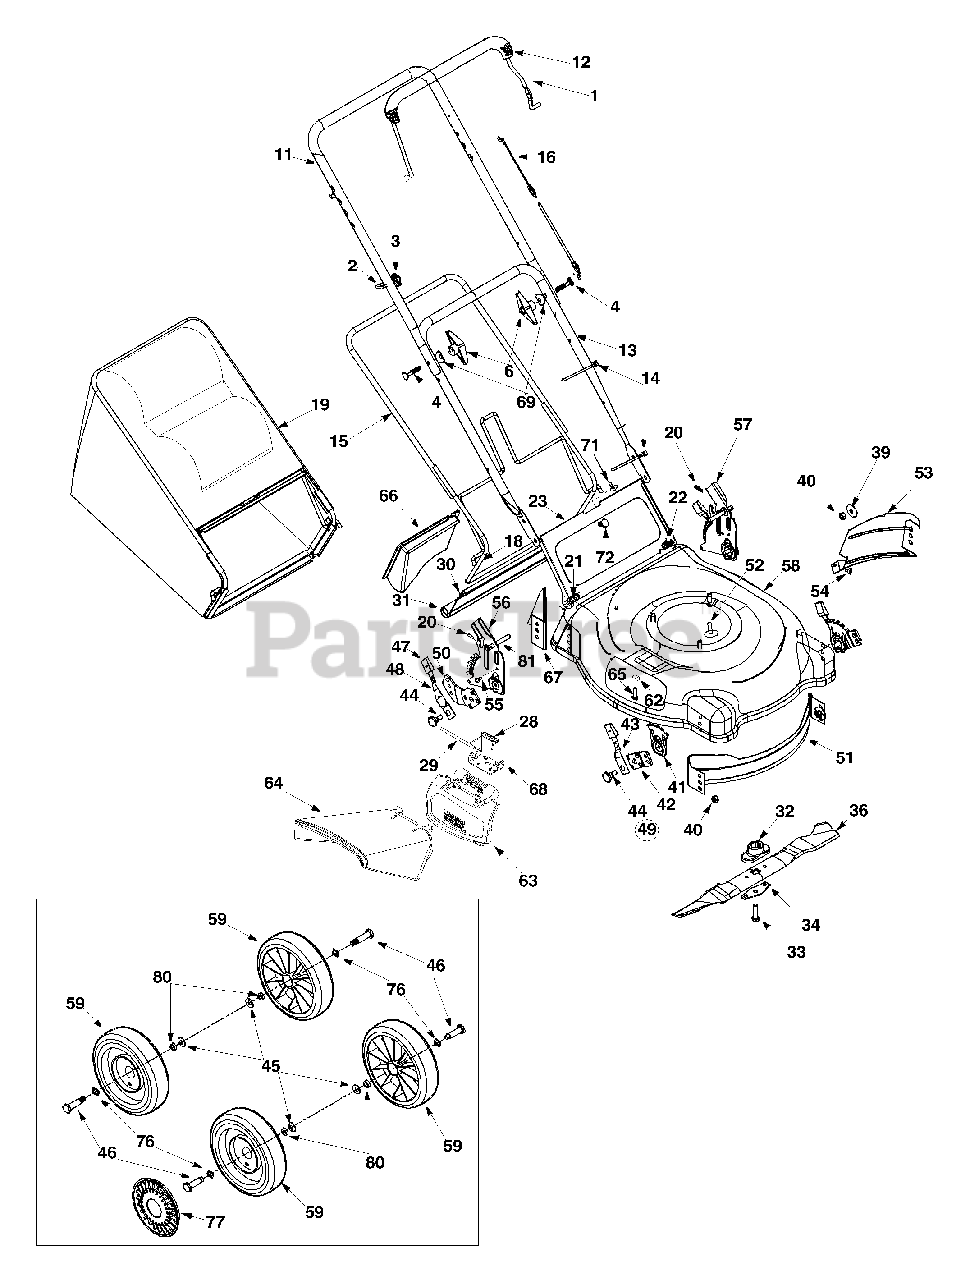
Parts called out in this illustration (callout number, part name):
2	Rope Guide
3	Handle Knob 1/4-20 Thd.
4	Curved Hd. Bolt 5/16-18 x 2"
6	Hand Knob
12	Bail Cover
14	Cable Tie
16	Control Cable - 40"
20	Int. Cotter Pin 5/16" Dia.
21	Door Spring - R.H.
22	Door Spring - L.H.
29	Hinge Pin
30	Wire Rod
31	Rear Flap
32	Blade Adapter
33	Hex Bolt 3/8-24 x 1.5" Lg.
34	Blade Bell Support
36	21" Mulching Blade
40	Flange Nut 3/8-16 Thd.
41	Height Adj. Plate
43	Front Spring Lever Ass'y. w/Knob
44	Shld. Bolt .5" Dia. x .357"
45	Bell Washer .38" I.D. x .88" O.D.
46	Axle Bolt
47	Spring Lever Knob
48	Rear Spring Lever
49	Height Adj. Assy. Comp. - RH
50	Pivot Bar R.H.
54	Torx Mach AB-Tap Scr. 1/4 x.62"
55	Hex Ind Wash. Scr. 1/4-14:.625
56	Handle Brkt. Ass'y.-RH
57	Handle Brkt. Ass'y.-LH
62	Bell Washer 1/4" I.D.
63	Hinged Mulching Plug
64	Chute Deflector: Side Discharge
65	Hex Hd Self-Tp Scr. 1/4-20 x .5"
66	Mulching Baffle Plug
69	Saddle Washer
71	Truss Scr. #10-24 x .38" Lg.
76	Wave Washer
77	Hub Cap:Grey
80	Spacer
